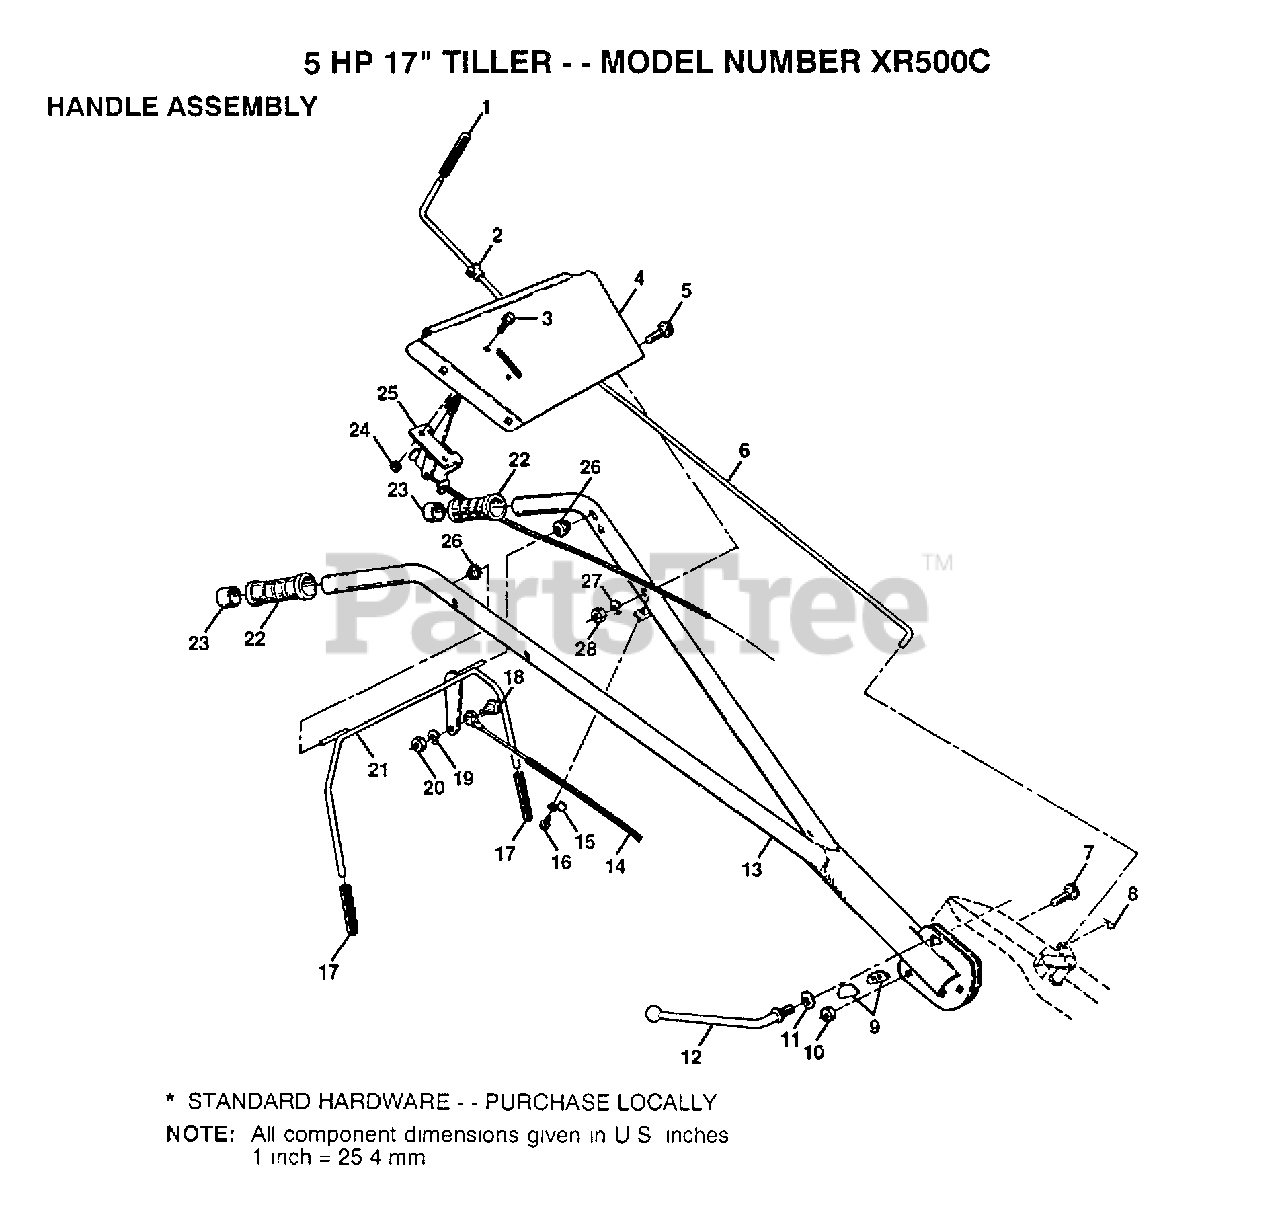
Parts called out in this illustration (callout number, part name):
1	GRIP TI
2	BUSHING
3	SCREW
4	"BRKT,HDLE TI"
5	BOLT CARRIAGE CRT
6	ROD SHIFT CRT
7	BOLT D
8	RETAINER M
9	LOCK CRT
10	LOCKNUT
11	WASHER CRT
12	LEVER LOCK CRT
14	CABLE.CLUTCH.CRT
15	CONDIUT CLIP T
17	GRIP BAR CRT
18	SHOULDER BOLT ST
19	LOCKWASHER
21	HANDLE BAR CRT
23	CAP CRT
25	"CONT,THROTTLE"
27	LOCKWASHER
